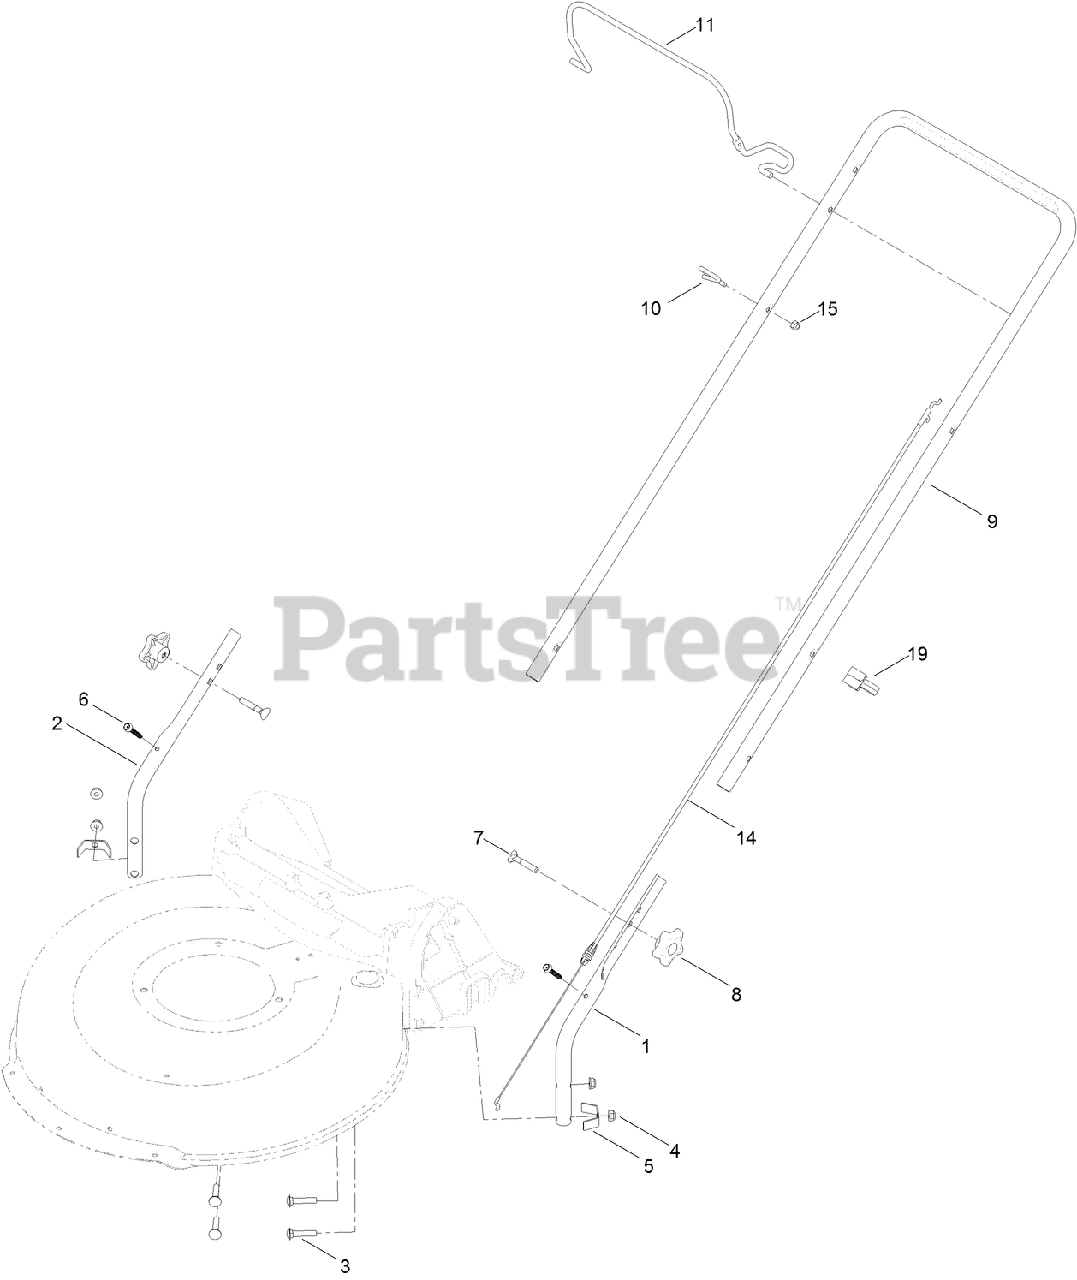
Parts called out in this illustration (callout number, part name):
3	BOLT-CARR
4	NUT-FLANGE, NI
5	BRACKET-CHUTE
6	SCREW-FLANGE, SERRATED
7	SCREW-HANDLE
8	KNOB-HANDLE
9	HANDLE-UPPER
10	GUIDE-ROPE
14	CABLE-BRAKE, ENGINE
15	NUT-LOCK, NI
19	GUIDE-CABLE
